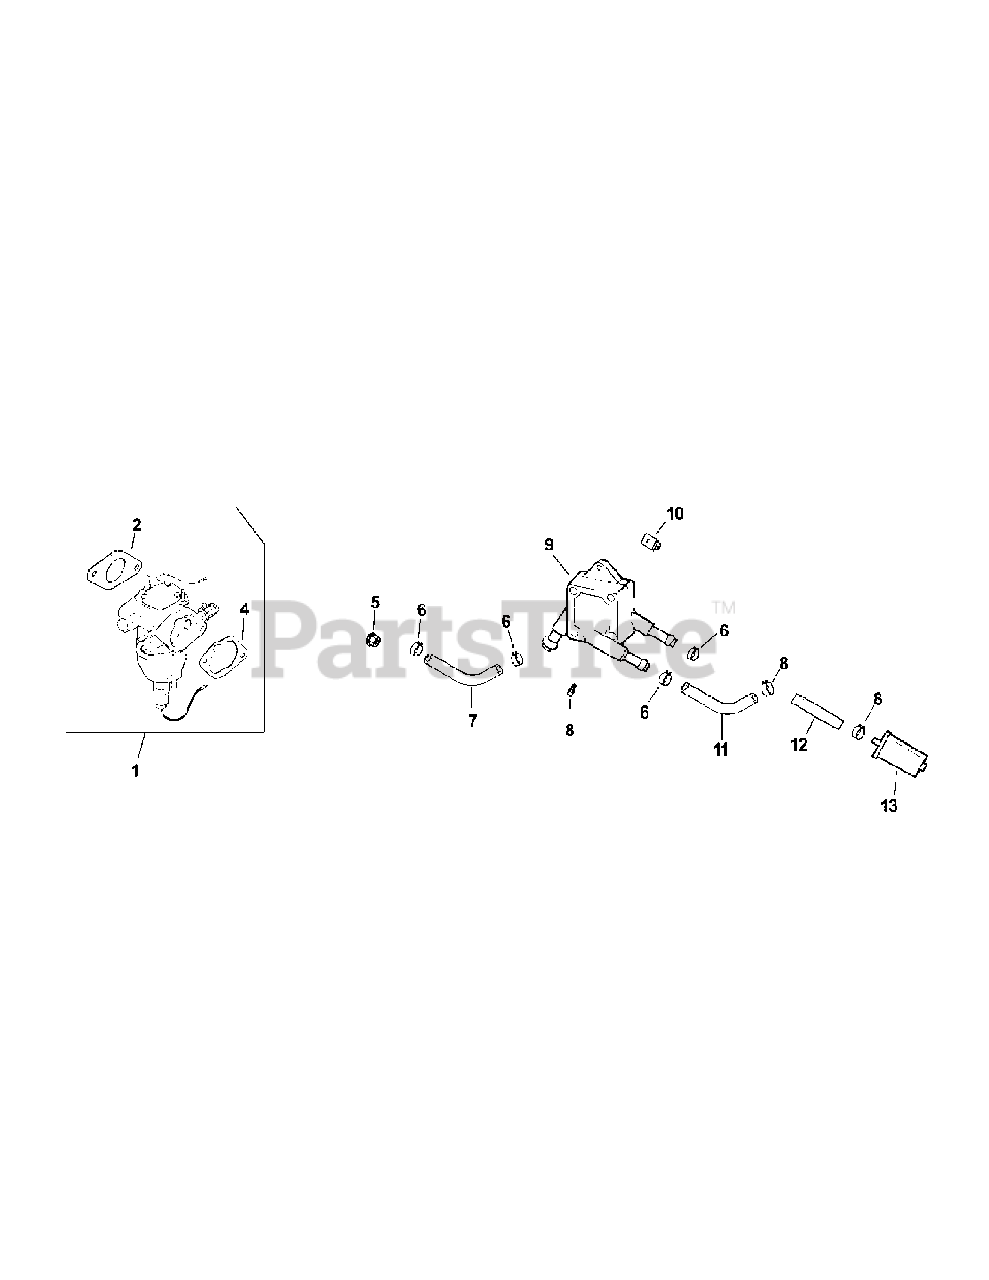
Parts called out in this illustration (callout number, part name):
1	Carburetor w/Gaskets
2	Carburetor Gasket
4	Air Cleaner Base Gasket
5	Hex Flange Nut (M6 x 1.0)
7	Fuel Line (12-1/2")
8	Hex Cap Screw (M6 x 1.7 x 18)
11	Fuel Line (10-1/2")
12	Fuel Line (3-1/2")
